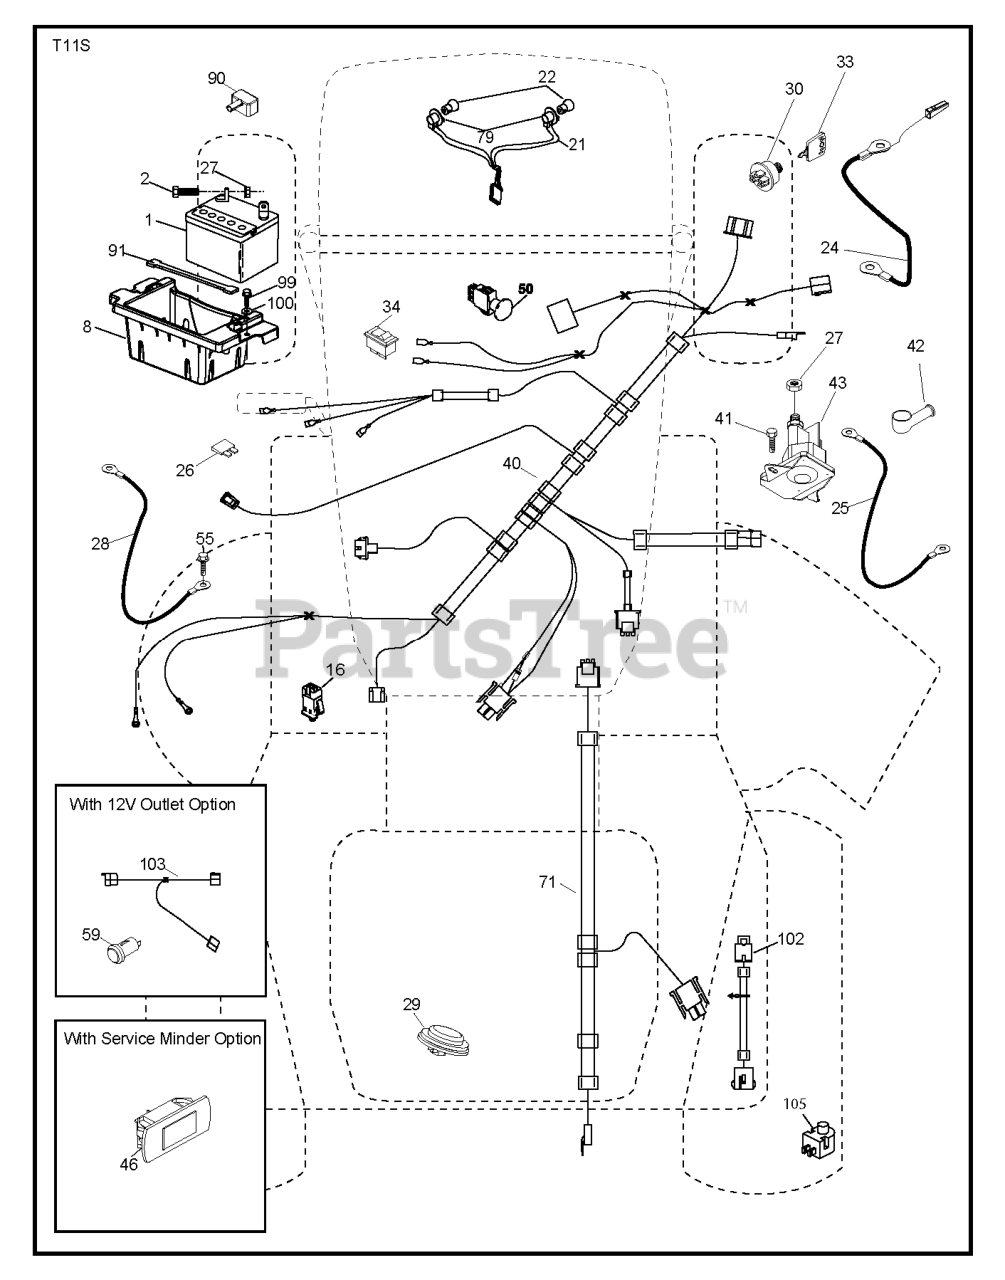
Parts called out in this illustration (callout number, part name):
1	Battery 12 Volt 25 Amp
2	BOLT.HEX.1/4.X.3/4.DICHROMATE
8	BOX.BATTERY.MOUNT.FRONT.LT
16	SWITCH INTERLOOK PUSH-IN
21	HARNESS ASSY LIGHT
24	CABLE.BATT.POS.WIRE.TG.DA SOL
25	CABLE.STARTER.6G.BL/RED.17.5
26	FUSE 20AMP
27	NUT
28	CABLE GROUND 6 GA 21" 90T BLK
29	SWITCH.SEAT.DELTA.OPC.
30	SWITCH.IGN.DELTA.W.LGH.ROS
33	KEY.CHAIN.BLISTER.PACK.GEN.USA
40	HARNESS.IGN.DASH.HUQ/P
41	SCREW
42	TERMINAL COVER
43	SOLENOID.W/BRASS.PLUNGER
46	RP.GUAGE.SRVCMNDR.HRMTR.
50	RP.PTO.SWITCH.8 TERMINAL.BLACK
55	SCREW 5/16"
59	OUTLET.12-VOLT
71	HARNESS-CHASSIS SUB
79	BULB HOLDER ASM.
90	COVER.TERMINAL.BATTERY
91	STRAP.BATTERY.MOUNT.FRONT(2 2)
99	SCREW HEXWSHR 1/4-20X3/4
102	HARNESS PIGTAIL PCH TEX ROS
103	HARNESS PIGTAIL 12V OUTLET
105	REVERSE SWITCH
